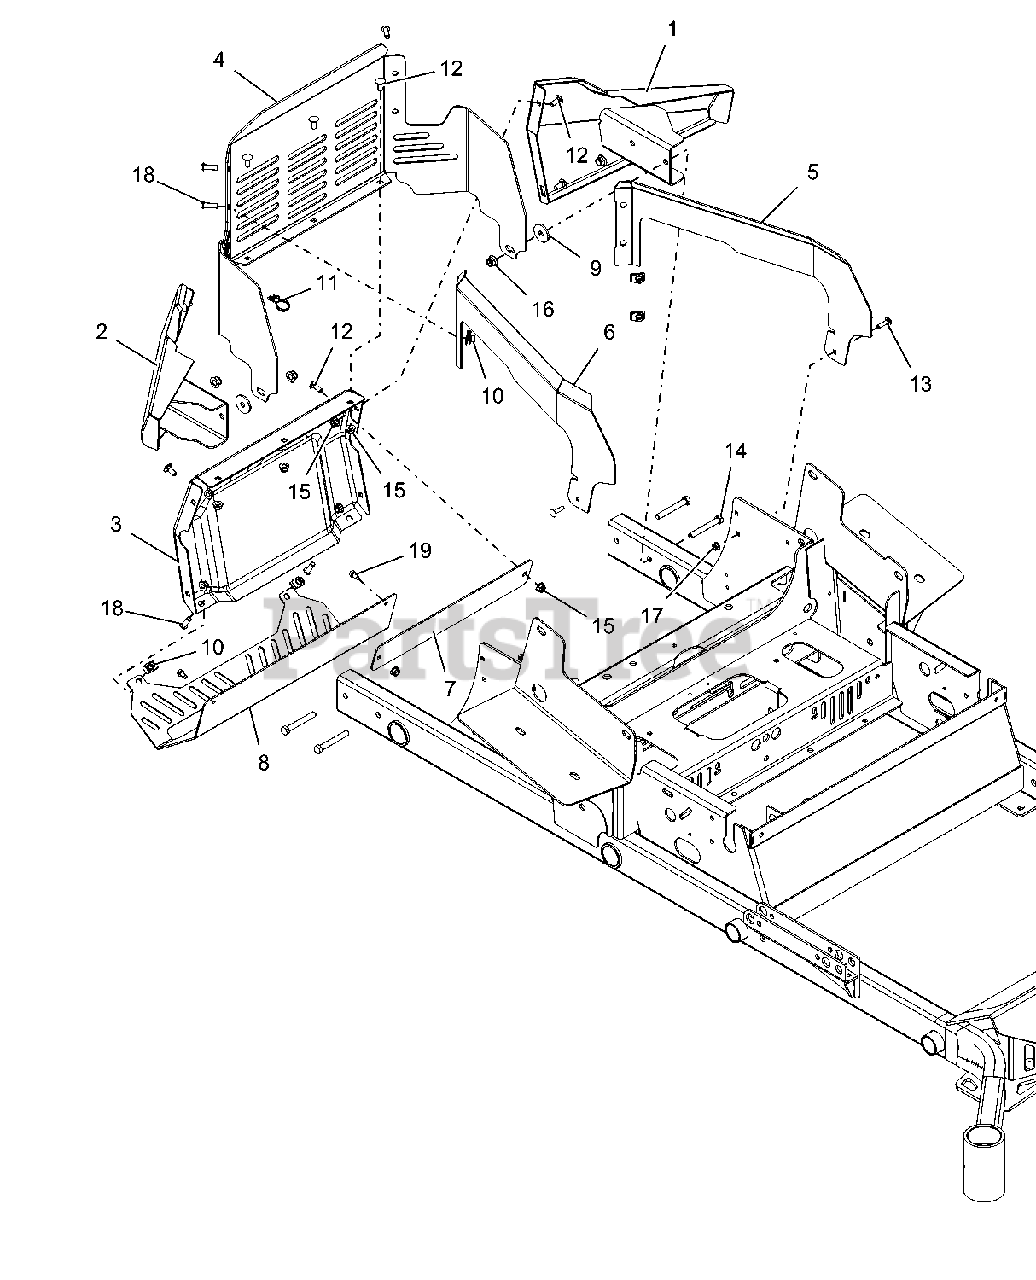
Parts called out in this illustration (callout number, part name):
1	WLDMT, LEFT REAR BUMPER WING (BLACK)
2	WLDMT, RIGHT REAR BUMPER WING (BLACK)
3	BUMPER, PT200/400 REAR (BLACK)
4	GUARD, PT400 ENGINE (BLACK)
5	TRIM, HOOD STYLE (LEFT) (RED)
6	TRIM, HOOD STYLE (RIGHT) (RED)
7	PLATE, BACKER (RED)
8	GUARD, PT200/400 MUFFLER (BLACK)
9	WSHR-FL-STL .406X1.375X.135 YZ
10	NUT-CLIP RETAINER 5/16-18X.56
11	CABLE TIE W/ TREE (.25 HOLE)
12	BLT-RDHDSQNK .31-18X.75 G5 YWZC
13	BLT-RDHDSQNK .25-20X1.00 G5 YWZC
14	BLT-HEX .38-16X2.75 GR5 YWZC
15	NUT-LK-NYL-FLG .31-18 YWZC
16	NUT-LK-NYL-FLG .38-16 YWZC
17	NUT-LK-NYL-FLG .25-20 YWZC
18	SCR-SKH .31-18X1.00 BTNHD YWZC
19	SCR-TAP .25-20X.50 HWH TR YWZ
